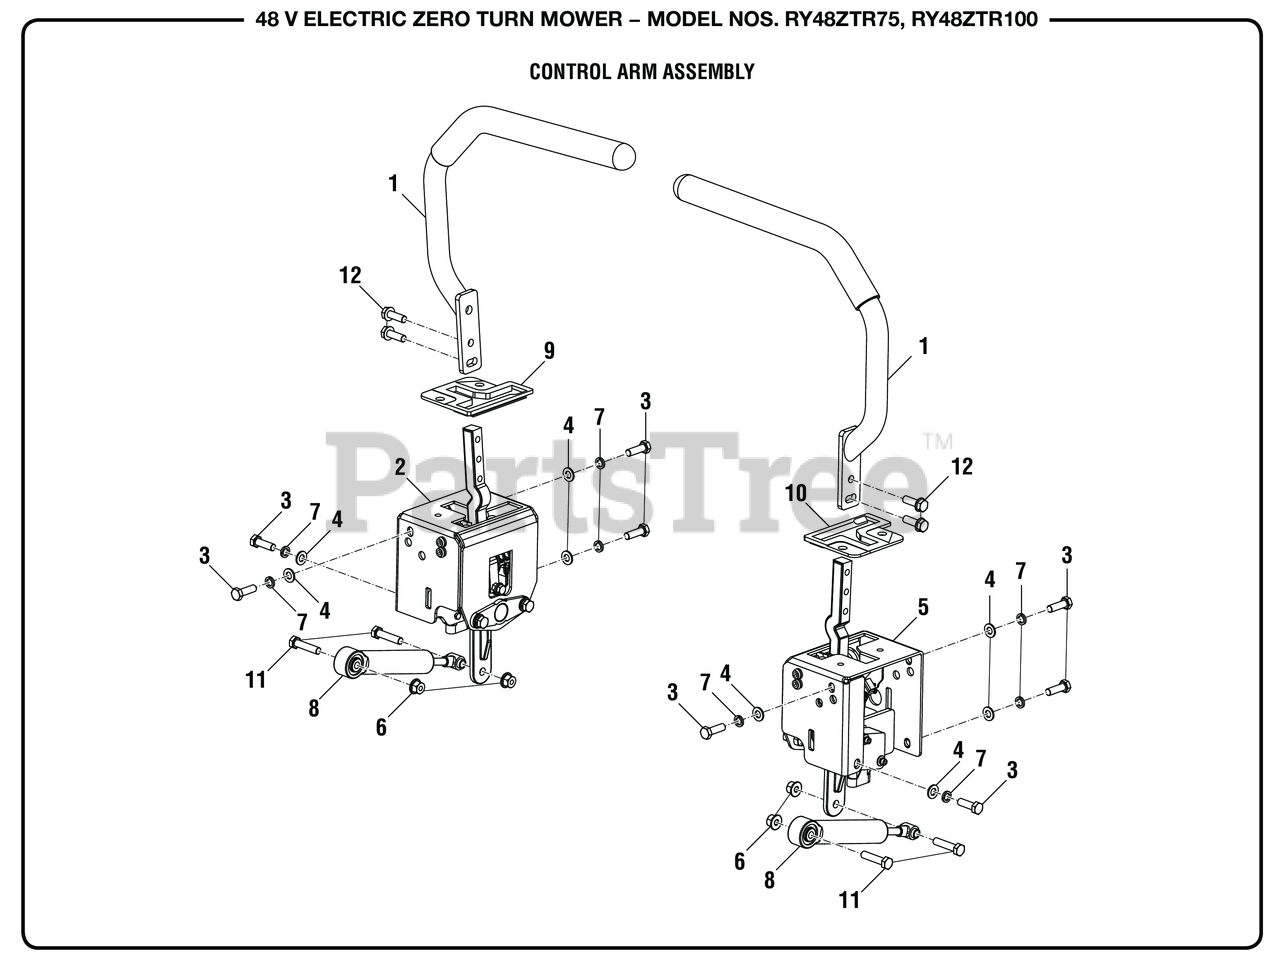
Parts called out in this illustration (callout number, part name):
1	Control Arm Handle
2	Control Arm Assembly, Left
3	Bolt (M8 x 25 mm, Hex Hd.)
4	Washer (OD16 x ID8.4 x 1.6t)
5	Control Arm Assembly, Right
6	Flange Nut (M8) (For Drive Motor Controller V)
7	Lock Washer (OD9.8 x ID8.5 x 5t)
8	Control Arm Damper
9	T Slot Insert, Left
10	T Slot Insert, Right
11	Bolt (M8 x 35 mm, Hex Hd.)
12	Bolt w/Washer (M8 x 25 mm, Hex Hd.)
